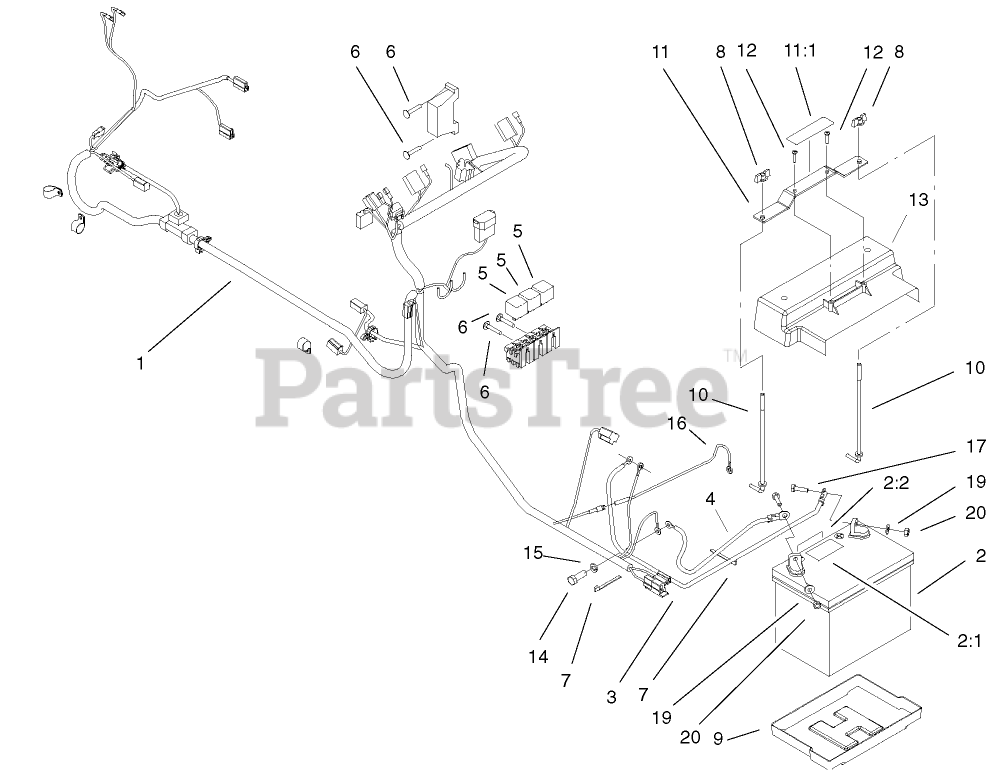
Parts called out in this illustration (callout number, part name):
1	HARNESS-WIRE
2	BATTERY-DRY
2:1	Decal-Battery
2:2	Decal-Battery
3	CABLE-BATTERY, RED 27IN
4	CABLE-BATTERY
5	RELAY
6	SCREW
7	TIE-CABLE
8	NUT-WING
9	TRAY-BATTERY
10	HOOK-RETAIN, BATTERY
11	STRAP ASM
11:1	DECAL-SURFACE, HOT
12	SCREW-PPH
13	SHIELD - BATTERY
13	SHIELD-BATTERY
14	SCREW-HHF
15	WASHER-LOCK
16	HARNESS-WIRE
17	SCREW-HH
19	WASHER-FLAT
20	NUT-LOCK, NI
